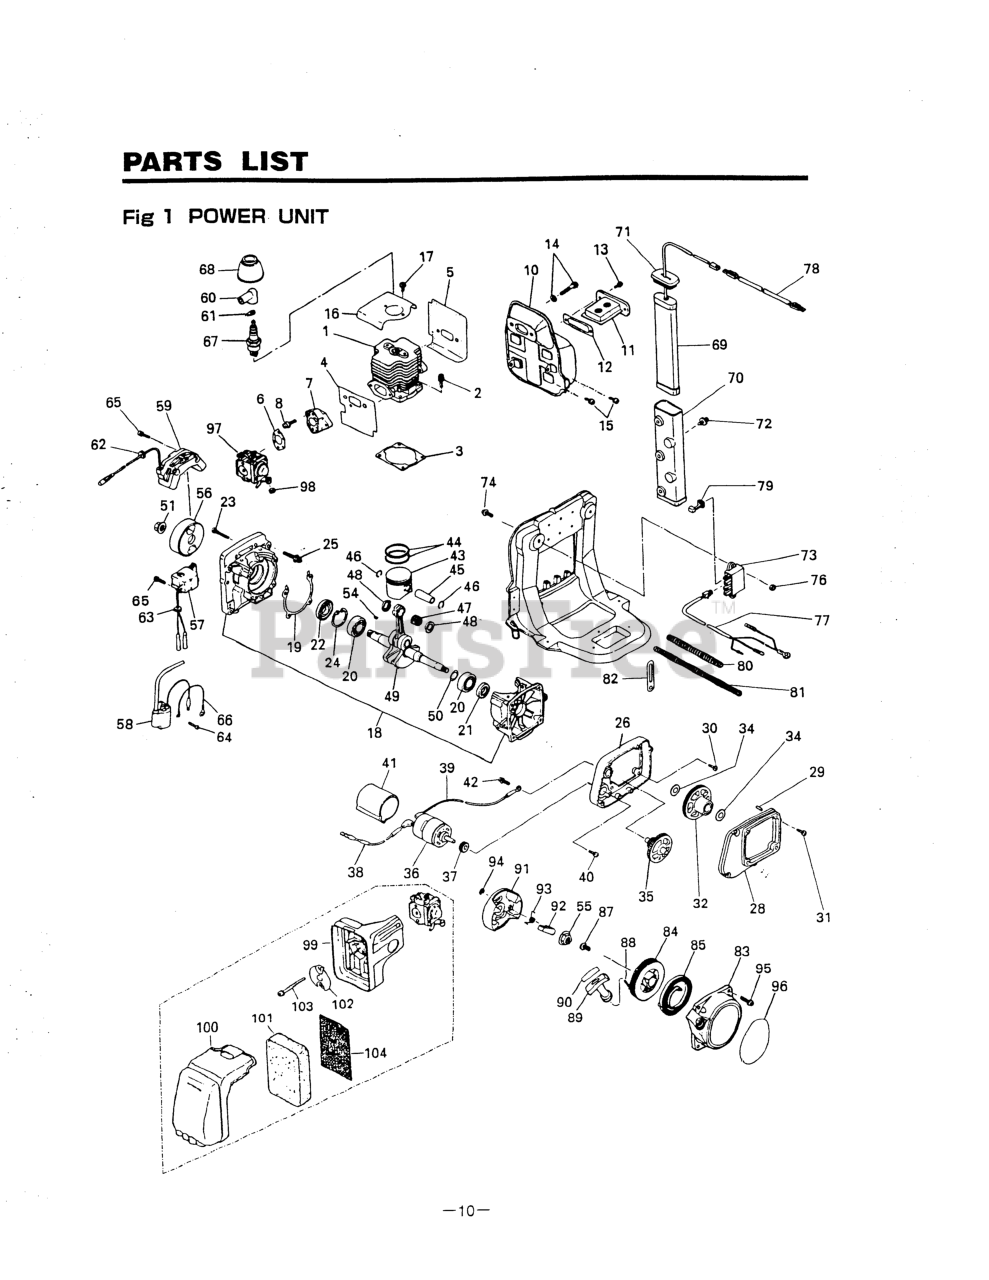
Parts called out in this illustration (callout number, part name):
1	CYLINDER (RPLS -12111)
2	BOLT, M5 x 22
7	INSULATOR (RPLS-14112)
10	MUFFLER (RPLS -15101)
11	ARRESTER
13	SCREW, M4 x 10
18	CRANKCASE COMP.
21	SEAL, OIL - STARTER SIDE
23	BOLT, M5 X 30
24	RING, SNAP, M35 X 1.5
25	BOLT (RPLS -21510)
26	GEARCASE COMP.
28	COVER COMP.
29	PIN, DOWEL
31	SCREW, M4 X 16
35	GEAR (B) (RPLS-23201)
36	MOTOR
37	GEAR (RPLS -24150)
38	CORD (YELLOW)
39	CORD (BLACK)
40	SCREW, M4 x 10
41	COVER, MOTOR
42	BOLT, M5 X 12
44	RING, PISTON (RPLS -41210)
46	RING, SNAP
47	BEARING
48	WASHER (RPLS 1491-41510)
50	SHIM (REPLACES 848-870-G000)
51	NUT, M10
54	KEY
58	COIL, IGNITION
59	COIL, GENERATOR
61	SPRING
63	GROMMET
64	SCREW, M4 x 16
65	SCREW (REPLACES -30414)
66	CABLE COMPLETE
68	CAP (NO LONGER AVAILABLE)
69	BATTERY
72	CLIP
73	RELAY
74	BOLT
76	NUT, M5 X 4
77	CORD ASSEMBLY
78	CORD ASSEMBLY
83	RECOIL ASSEMBLY
84	REEL
85	SPRING, SPIRAL
87	SCREW (RPLS -75150)
89	KNOB
91	PULLEY ASSEMBLY
92	RATCHET
93	SPRING, RETURN
94	E-RING
95	SCREW, M5X20 (RPLS.1400-75510)
96	LABEL, RECOIL
98	CAP, CABLE END
102	PLATE, SHUT
103	SCREW, M5 X 55
